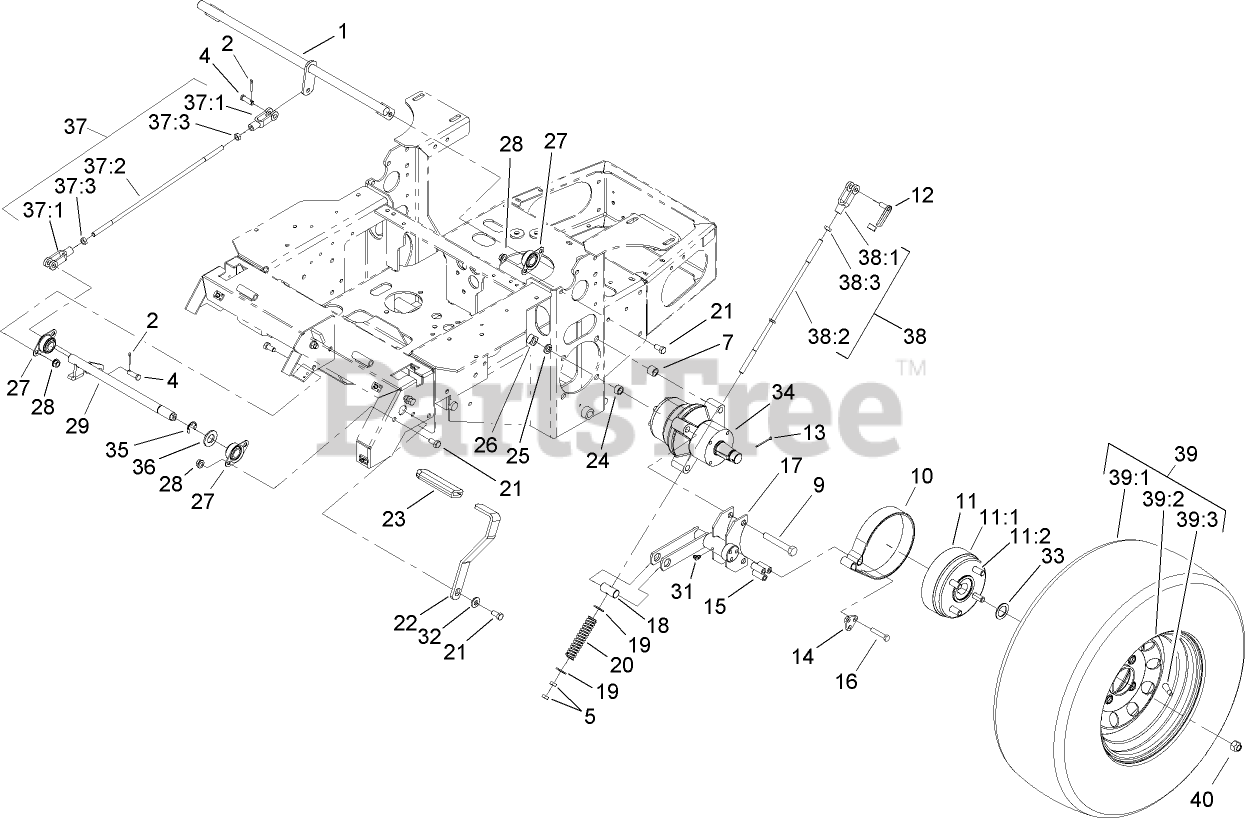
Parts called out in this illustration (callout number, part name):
1	CRANK-BRAKE, PARK
2	PIN-COTTER
4	PIN-CLEVIS
5	NUT-HEX
7	SPACER-WHEEL
9	SCREW-HH
10	BAND-BRAKE
11	WHEEL HUB ASM
11:1	HUB-WHEEL
11:2	STUD-WHEEL
12	Pin-Spring, Clevis
13	PIN-COTTER
14	RETAINER-BAND, BRAKE
15	SPACER
16	SCREW-HH
17	BRACKET-BRAKE
18	PIN-TRUNION
19	WASHER-FLAT
20	SPRING-BRAKE
21	SCREW-HH
22	HANDLE-BRAKE, PARK
23	GRIP-LEVER
24	SPACER-WHEEL
25	WASHER-LOCK
26	NUT-SQUARE
27	BEARING-FLANGE, SIDE
28	NUT-HHF, WHIZ
29	Shaft-Brake, Parking
31	FITTING-GREASE
32	WASHER-BELLEVILLE
33	WASHER-SPACER
34	MOTOR-WHEEL
35	E-RING
36	WASHER-FLAT
37	BRAKE ROD ASM
37:1	YOKE-LINKAGE, BRAKE
37:2	LINKAGE-HANDLE, BRAKE
37:3	NUT-HEX
38	BRAKE ROD ASM
38:1	YOKE-LINKAGE, BRAKE
38:2	ROD-BRAKE
38:3	NUT-HEX
39	WHEEL AND TIRE ASM
39:1	TIRE
39:3	STEM-VALVE
40	NUT-LUG
